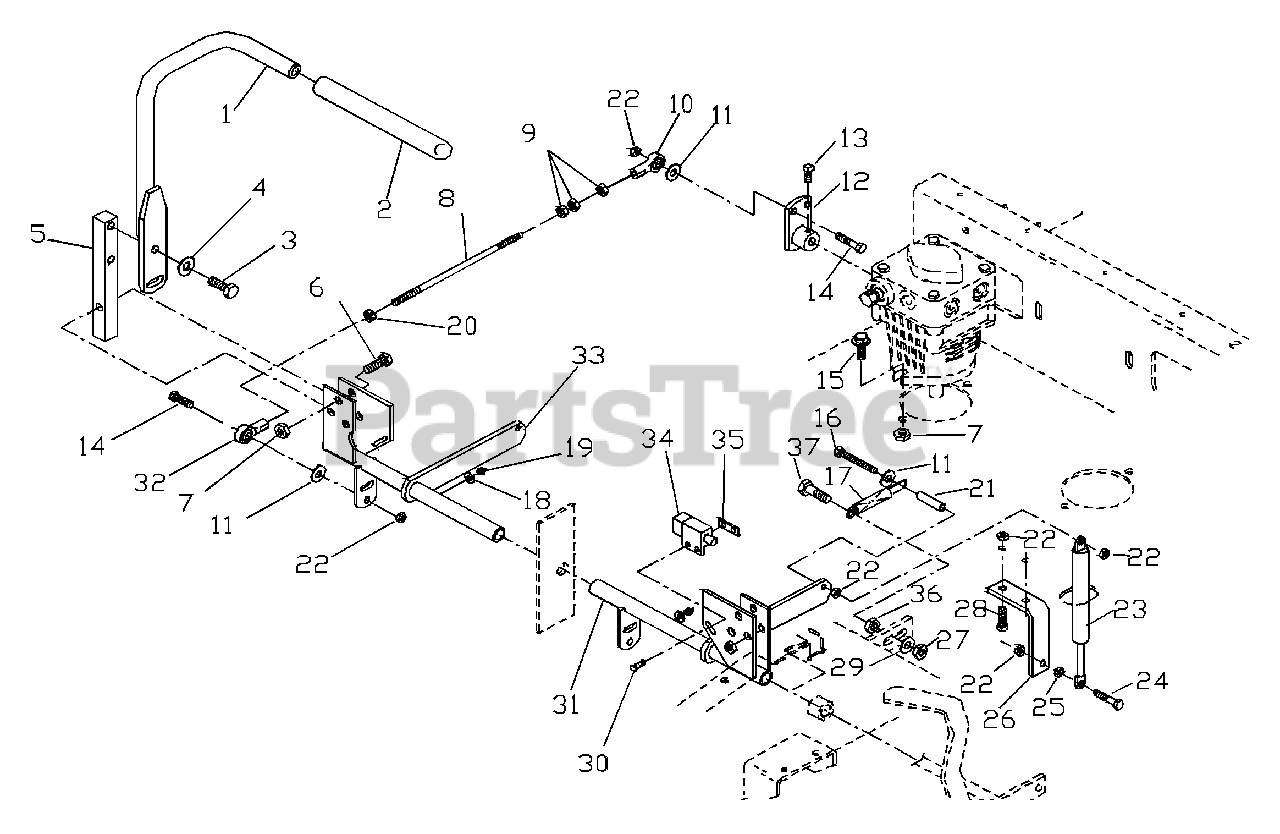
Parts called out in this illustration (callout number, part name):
1	CONT. LEVER
3	HCS 3/8C X 1
4	3/8 SPRING WASHER
5	ARM CONT. SHAFT
6	HCS 3/8C X 1 1/2
7	NUT 3/8C CTR. LOCK
8	PUMP CONTROL LINK
10	BALL JOINT RT.
11	5/16 FLAT WASHER
12	PUMP LEVER
13	5/16C X 5/8 "V" POINT
14	HCS 5/16C X 1
15	HCS 3/8C X 1
16	TAPBOLT 5/16C X 2.25
17	REV. DETENT SPRING
19	ZERK
20	NUT 5/16F LH.
22	5/16C CTR. LOCK
24	HCS 5/16C X 1.25
25	5/16C WHIZ NUT
26	BRACKET "L"
27	3/8C NYLOC
28	HCS 5/16C X 3/4
29	3/8 FLAT WASHER
30	SCREW #10-24 X 5/8
31	CONTROL WLDMT. LEFT
32	BALL JOINT LH.
33	CONTROL WLDMT. RIGHT
35	TAPPED PLATE
36	3/8C WHIZ NUT
37	HCS 3/8C X 2
38	HOSE CLAMP
